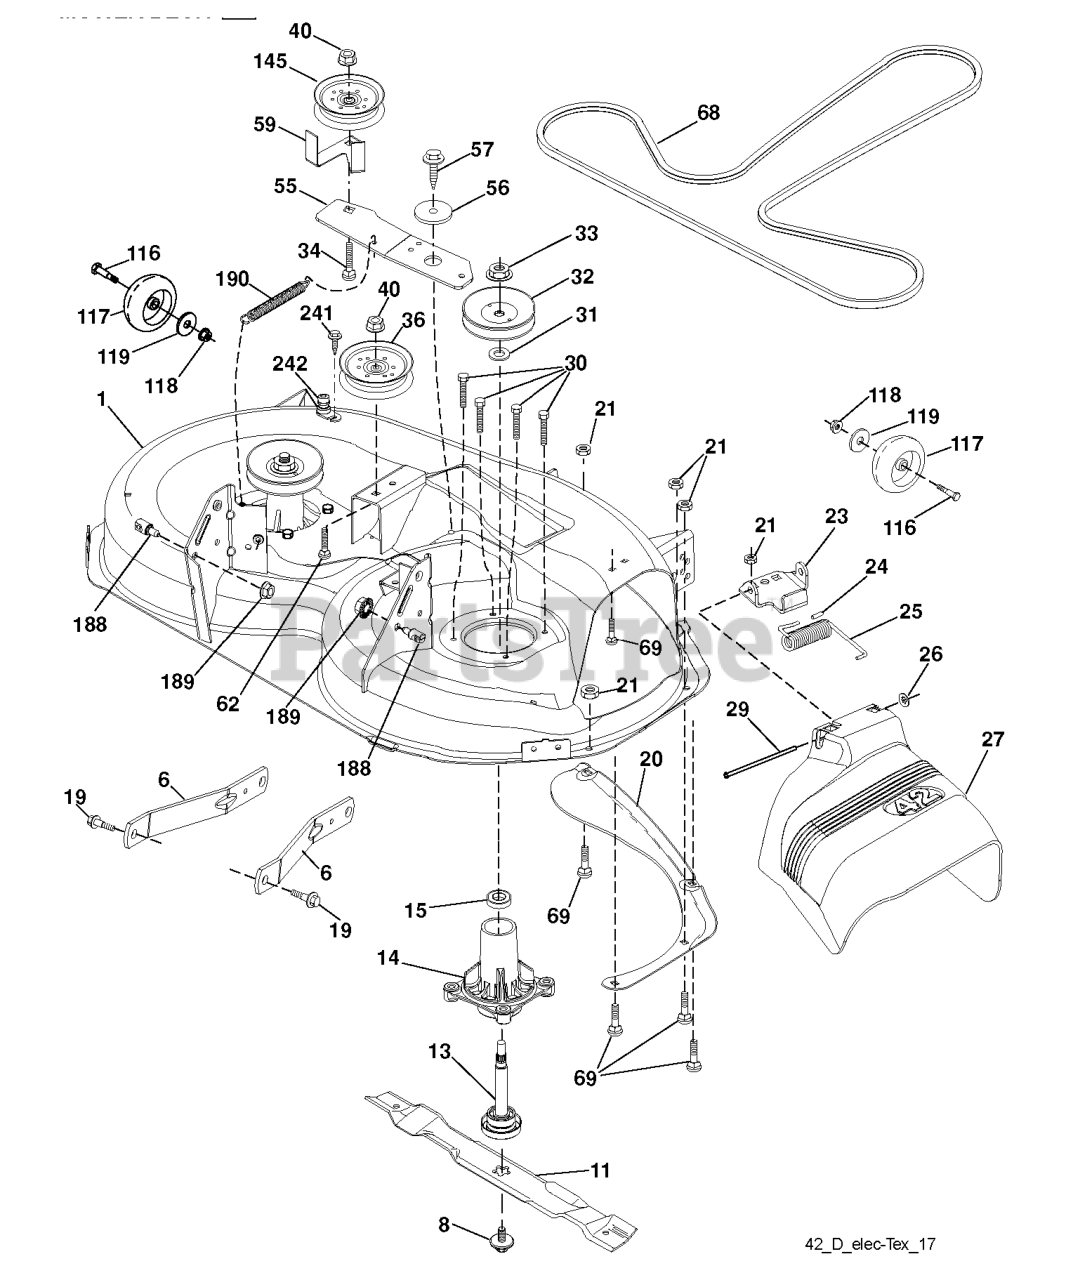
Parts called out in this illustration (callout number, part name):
1	DECK.WELDMENT.42"
6	ARM.SUSPENSION.MOWER.R
8	BOLT.WASHER.ASM.7/16-2
11	42" HI-LIFT BLADE
13	SHAFT.ASM.MDRL.N/GREASE.38
14	RP.HOUSING.MANDREL.4PT.
19	BOLT.SHOULDER
20	BAFFLE.VORTEX
21	LOCKNUT
23	BRKT.DEFLECTOR.38"2005+
24	CAP-SLEEVE LT
25	SPRING.TORSION.DEFLECT
26	NUT PUSH M
27	SHIELD.DEFLECTOR.MOWER.42"BLAC
29	ROD.HINGE
30	SCREW, WASHER HEAD
31	WASHER.SPACER.MANDREL
32	PULLEY/MANDREL
33	NUT.FLANGE.LOCK.TOP
34	BOLT.3/8-16X1.50
36	PULLEY.IDLER.2006
40	NUT LOCK FLG 3/8-16 UNC
55	IDLER.ARM.42"
56	SPACER.RETAINER
57	SCREW 3/8-16X1
59	GUARD, BELT
68	BELT V SECONDARY
69	BOLT
116	BOLT M
117	WHEEL.GAGE.HALF.SPOKED
118	NUT LOCK FLG 3/8-16 UNC
119	WASHER.5/16.FLAT.STE.STD.
145	PULLEY.IDLER.48"PRIMARY
188	STUD.FASTNER.W/ANTI-ROTATE
189	NUT LOCK HEX FLANGE 5/16-18
190	SPRING.MOWER.DRIVE.ELECTRIC
241	SCREW.TT.#10-32X.5.3/8.FLANGE
242	PORT.WASHOUT
